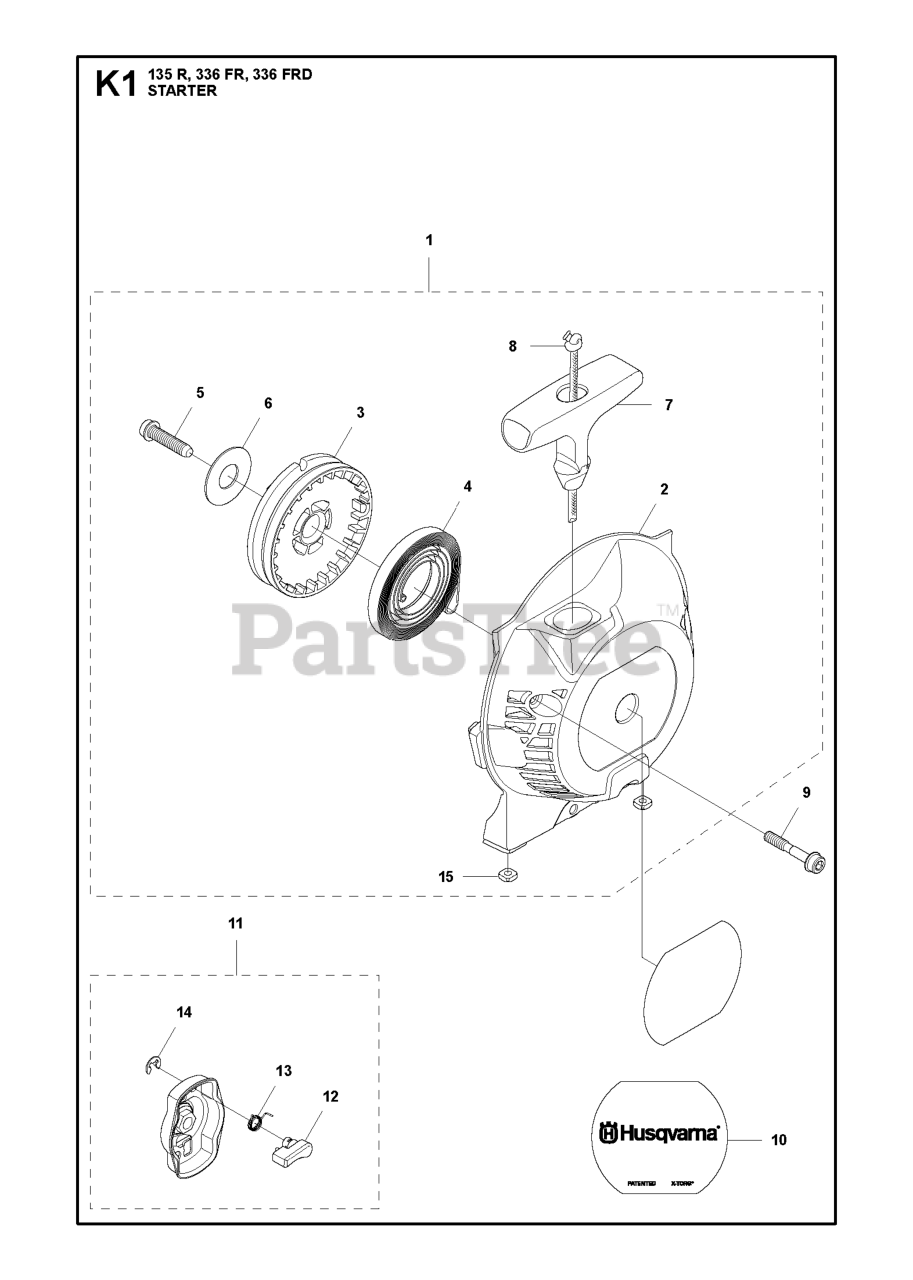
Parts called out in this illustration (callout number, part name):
1	STARTER ASSY
2	STARTER HOUSING
3	STARTER PULLEY
4	STARTER SPRING
8	STARTER ROPE
9	SCREW IHSCFMO
11	STARTER PAWL BRIDGE
12	STARTER PAWL
